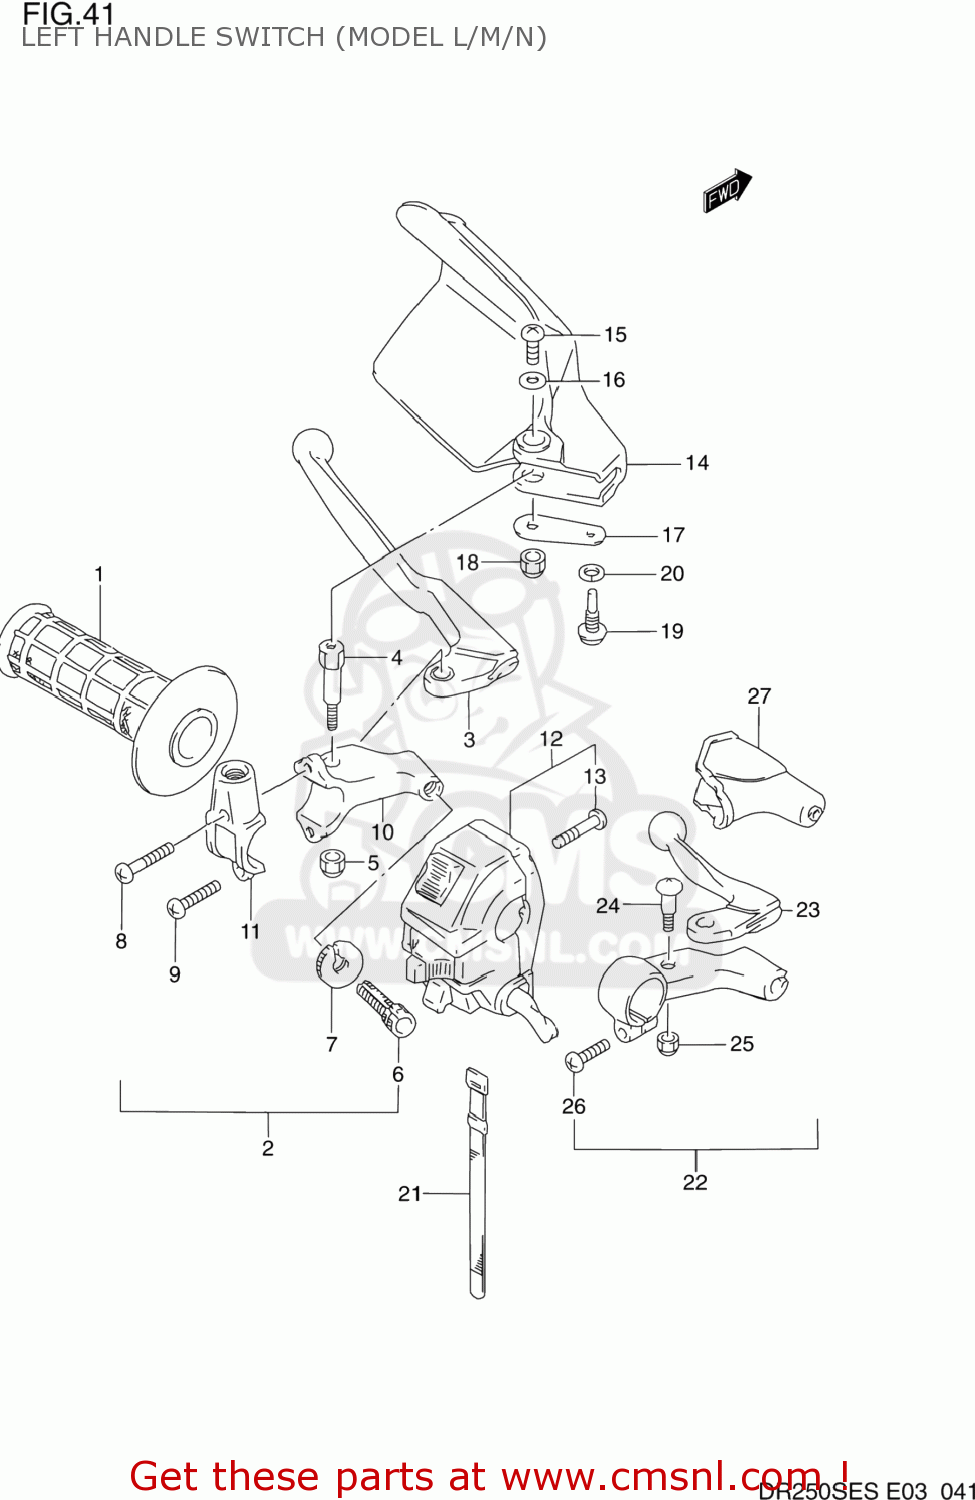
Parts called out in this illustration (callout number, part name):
1	GRIP,L
2	LEVER ASSY,CLUTCH
3	LEVER,CLUTCH
4	BOLT,LEVER SET
5	NUT 6MM
6	ADJUSTER,CABLE
7	NUT,LOCK
8	SCREW
9	SCREW(5X14)
10	HOLDER,CLUTCH LEVER
11	BRACKET,HOLDER
12	SWITCH ASSEMBLY,HANDLE,LEFT
13	SCREW
14	COVER,KNUCKLE,LEFT
15	SCREW(5X10)
16	WASHER (5.5X16X1.2)
17	PLATE,KNUCKLE COVER,L LWR
18	NUT 6MM
19	SCREW
20	WASHER,LOCK
21	CLAMP(L:120)
22	LEVER ASSEMBLY,DECOMPRESSION
23	LEVER,DECOMP
24	BOLT,LEVER PIVOT
25	NUT
26	SCREW
27	COVER,DECOMP LEVER DUST
